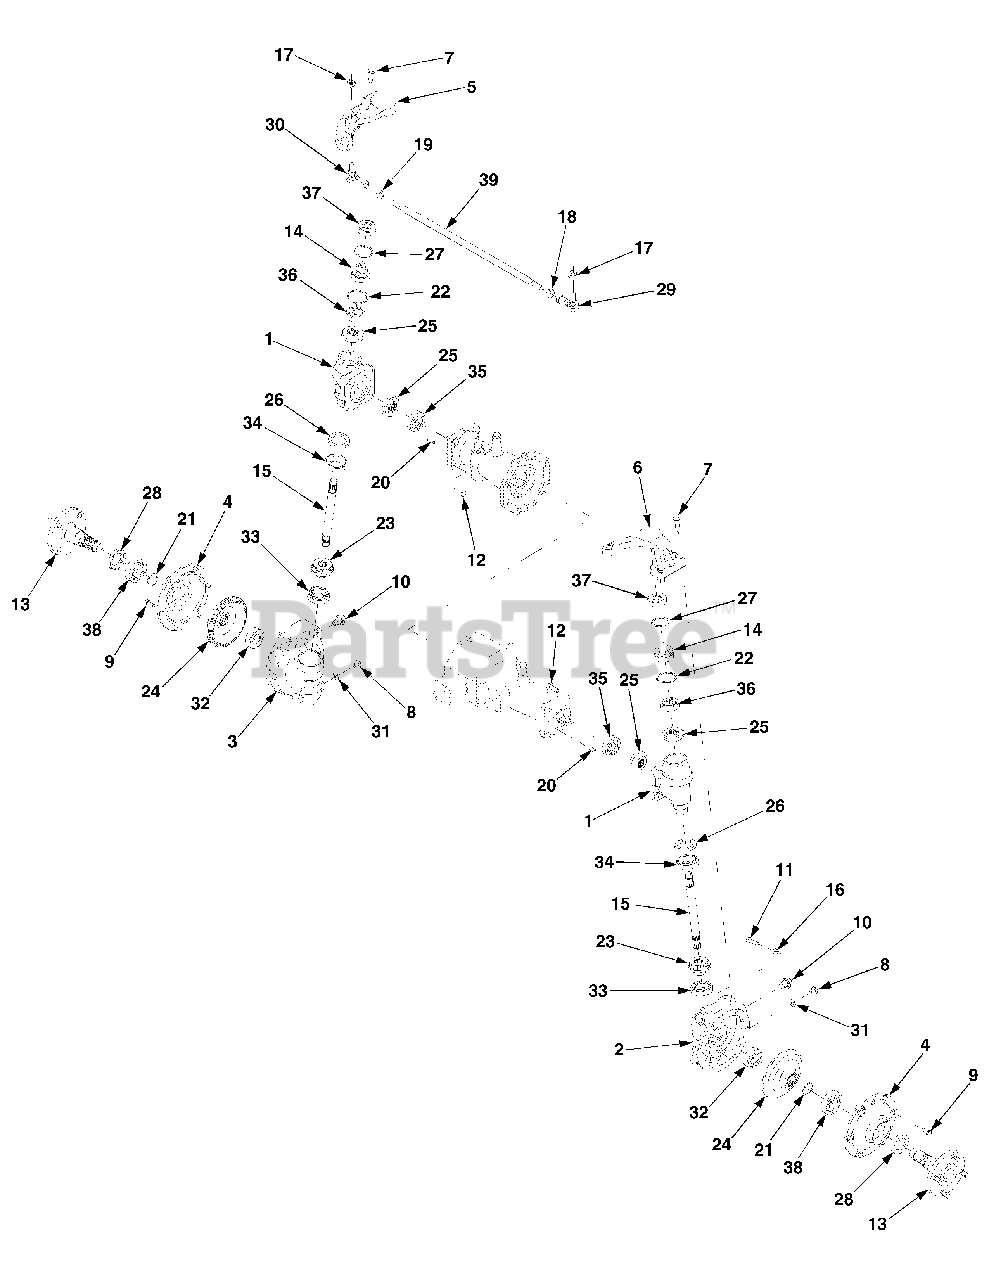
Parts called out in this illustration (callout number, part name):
1	Housing, Kingpin
2	Housing, Axle Drop, RH
3	Housing, Axle Drop, LH
4	Cover, Axle
5	Arm, Steering, LH
6	Arm, Steering, RH
7	Screw, Hex Cap, M10-1.5 x 35 GR8.8
8	Plug, Hex, 3/8-16 x .5
9	Screw, Hex Cap, M8-1.25 x 20 GR8.8
10	Plug, Screw, M14-1.5 x .827
11	Screw, Hex Cap, M8-1.25 x 30
12	Screw, Hex Cap, M10-1.5 x 25
13	Axle, Flange
14	Shaft, Stub
15	Shaft, Kingpin
16	Nut, Hex, M8-1.25
17	Nut, Hex Flange Lock, M12-1.75
18	Nut, Hex, M12-1.75 RH Thrd.
19	Nut, Hex, M12-1.75 LH Thrd.
20	Pin, Dowel, 8mm x 20mm
21	Ring, Retaining
22	Ring, Retaining
23	Gear, Bevel, 13T
24	Gear, Bevel, 34T
25	Gear, Bevel, 14T
26	Seal, Oil, 38 x 55 x 7 w/Dirt Lip
27	O-Ring, 40mm x 3mm
28	Seal, Oil, 35mm x 55mm x 8mm
29	Ball Joint, 12-1.75 RH
30	Ball Joint, 12-1.75 LH
31	Washer, Flat, .39 x .75 x .062
32	Bearing, Ball
33	Bearing, Ball
34	Bearing, Tapered Roller w/ Race
35	Bearing, Ball
36	Bearing, Ball
37	Bearing, Ball
38	Bearing, Ball
39	Rod, Tie, M12-1.75
